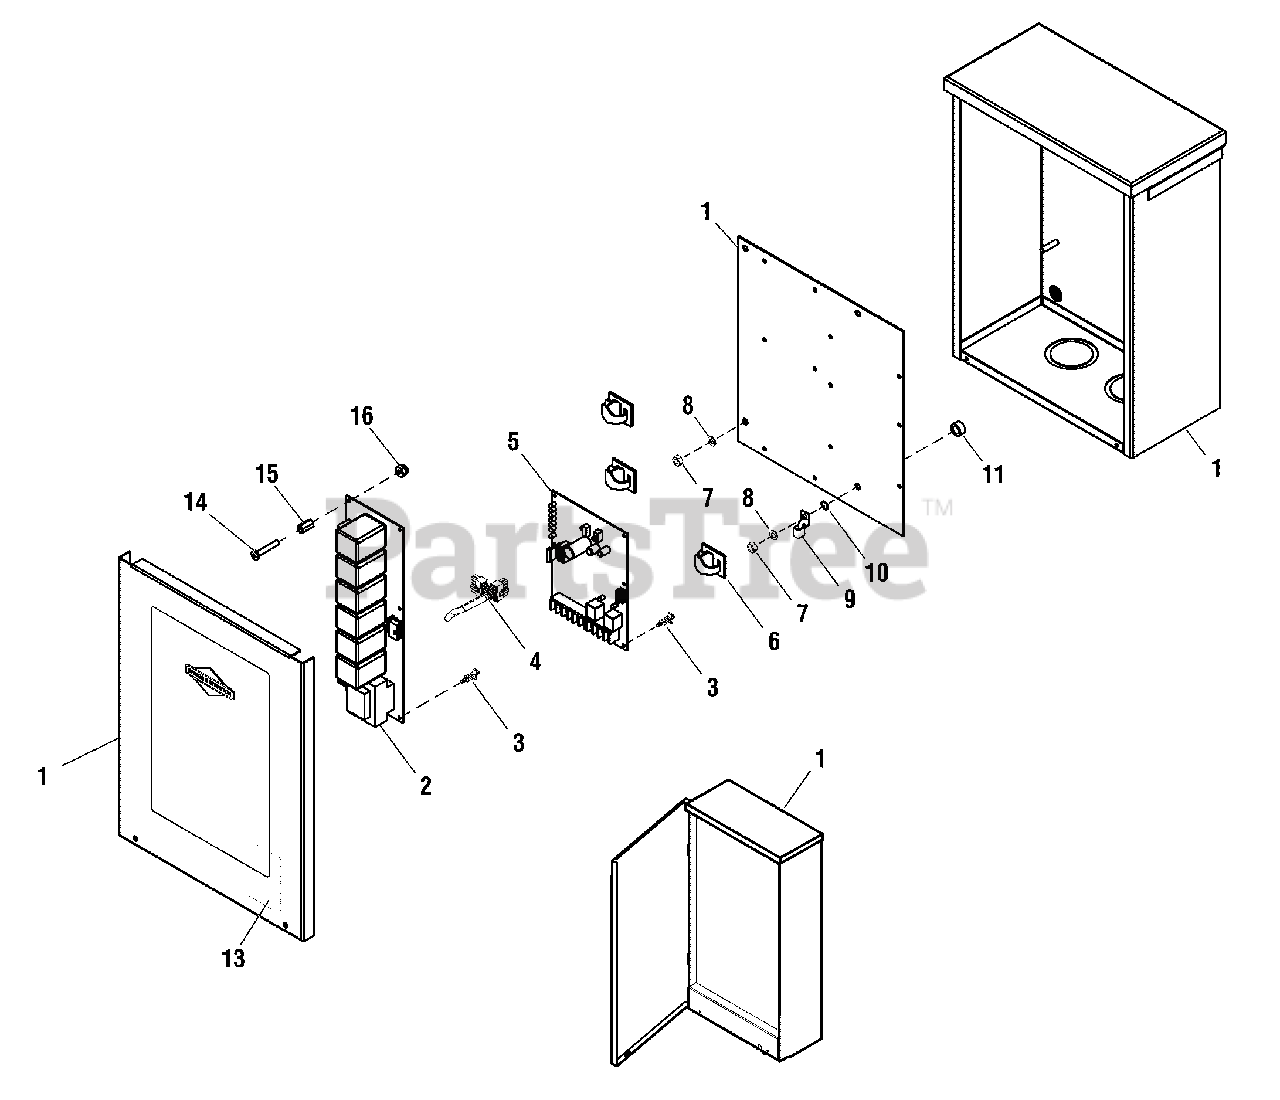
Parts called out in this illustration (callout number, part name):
1	ENCLOSURE
2	BOARD, Load Control Center Relay
3	SPACER, PCB Bard, 1/2"
5	BOARD, Load Control Center
6	CLIP, Latching Wire
7	* NUT, 1/4-20
8	* WASHER, Lock, 1/4
10	* WASHER, Shakeproof, Ext, M6-1/4
11	SPACER
14	* SCREW, Phillips Head, 8-32 x 1
15	SPACER, 4 x 25
16	* NUT, Hex Lock, 8-32
